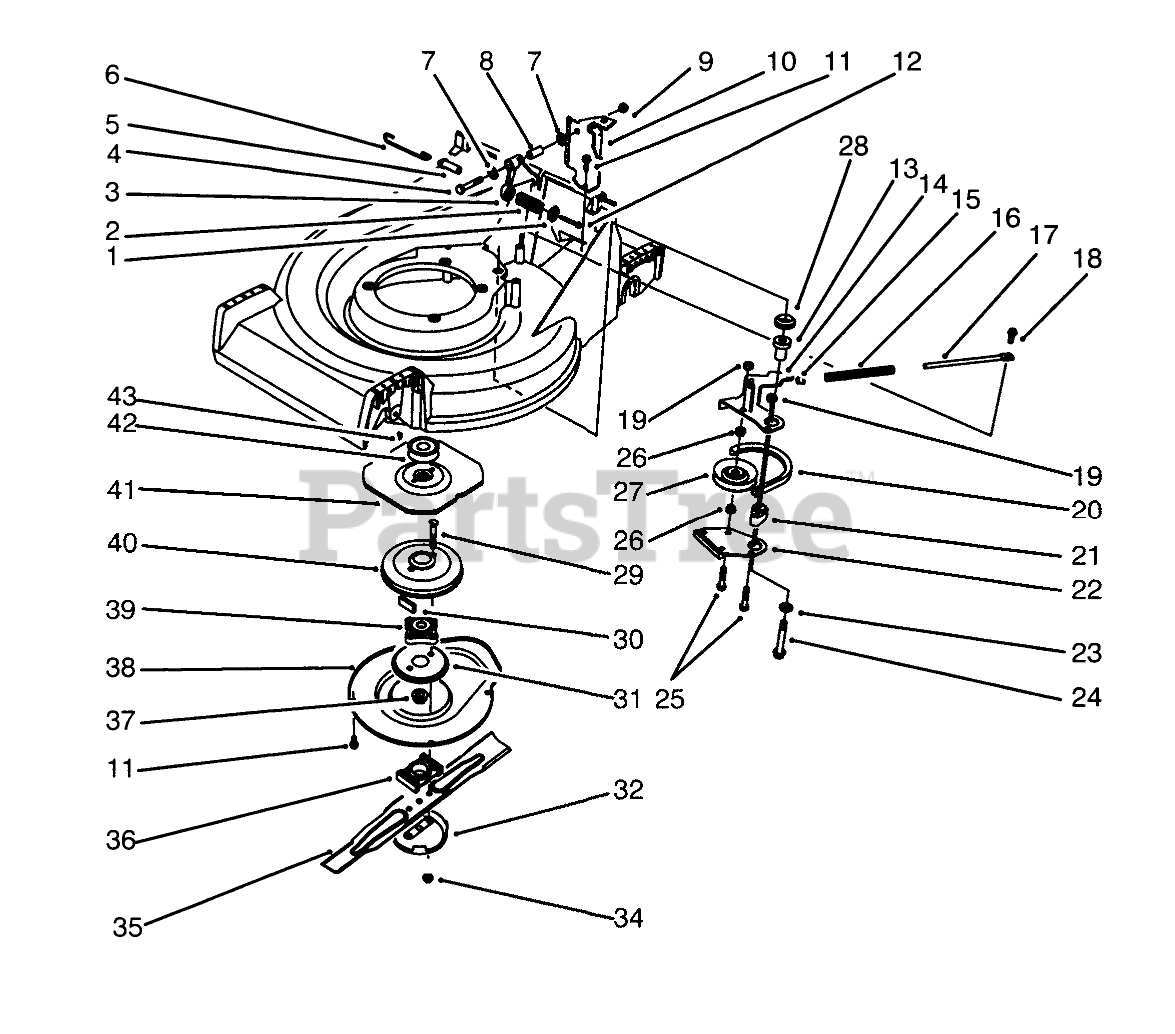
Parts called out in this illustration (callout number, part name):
1	RETAINER-SPRING
2	COMPRESSION SPRING
3	CRANK
4	SCREW-HH
5	SPRING PIN
6	CONTROL LINK
7	WASHER-PLAIN
8	STRAIGHT BUSHING
10	Bracket-Cable Support
11	SCREW-HWHTF
12	SCREW-HWHTF
13	BBC PM BUSHING
14	Lever
15	SPACER
16	COMPRESSION SPRING
17	SPRING ROD
18	SCREW-SHOULDER
19	NUT-LOCK, NI
20	V-BELT
21	BRAKE PLATE HUB
22	BRAKE SHOE
23	WASHER-PLAIN
24	THD FORM SCREW
25	SCREW-HH
26	IDLER PULLEY HUB
27	PULLEY-IDLER
28	V-RING SEAL
29	BOLT-BLADE
30	DAMPENER-VIBRATION
31	Screen-BBC
32	CUP-SCALP, ANTI
34	NUT-LOCK
35	Key
36	SPACER-BLADE
37	NUT-LOCK, NI
38	Cover
39	HUB ASM
40	BRAKE DRUM
41	FLYWHEEL - BBC
42	PULLEY
43	KEY-WOODRUFF
